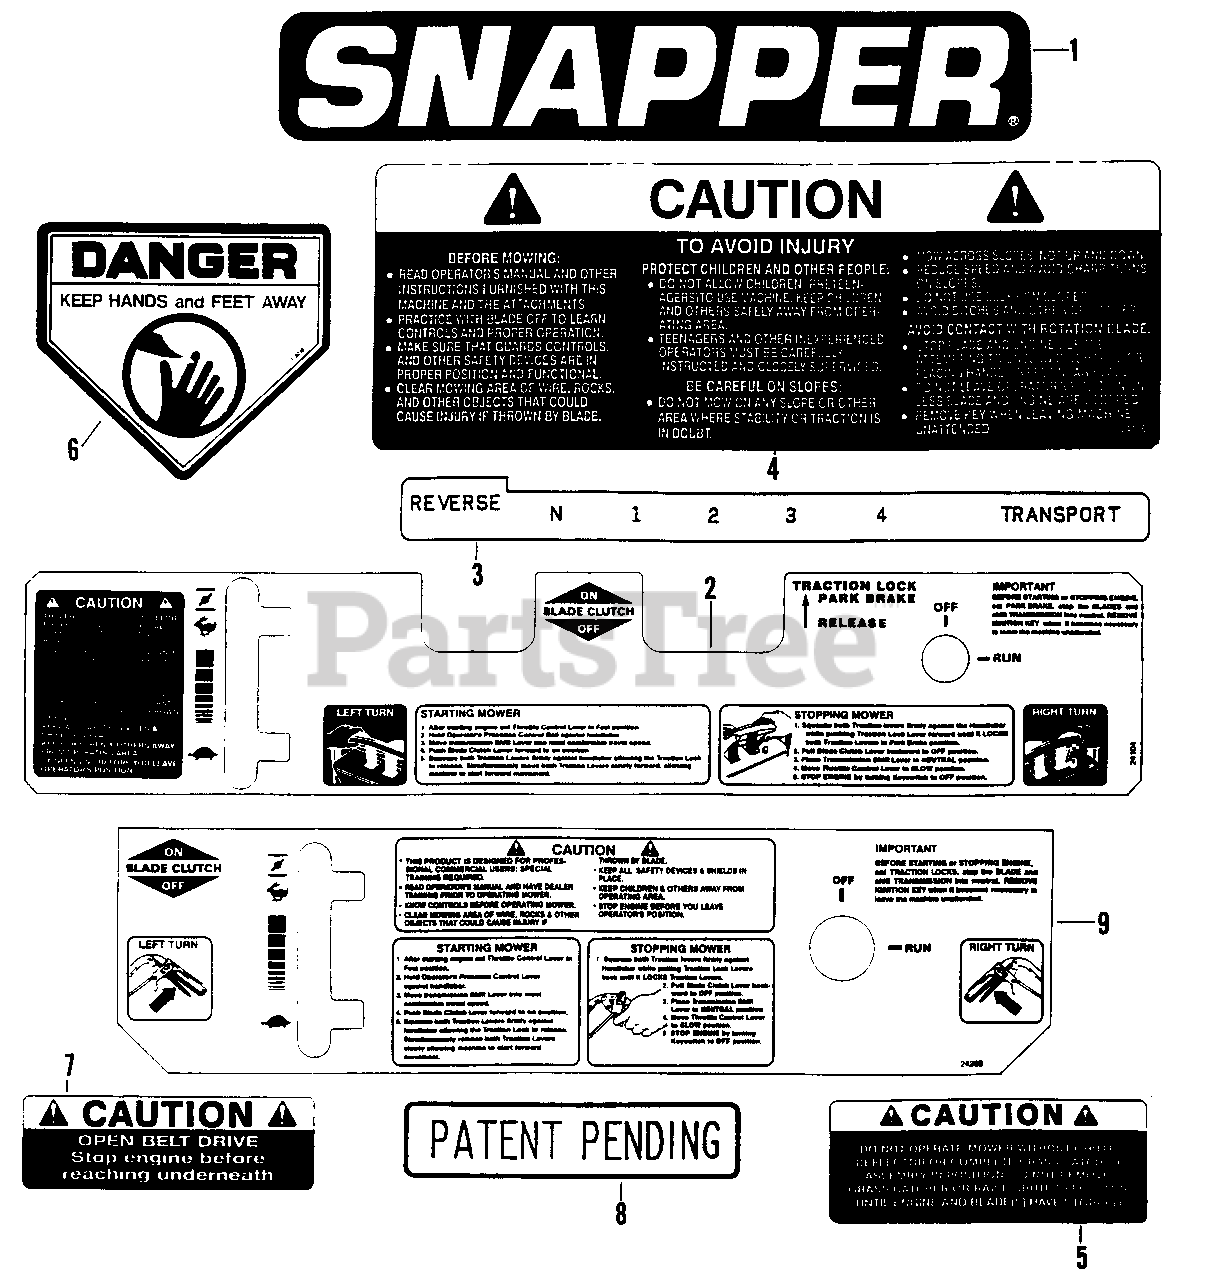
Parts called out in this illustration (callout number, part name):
1	DECAL, SNAPPER
2	DECAL, CONSOLE
3	DECAL, SHIFT QUAD
4	DECAL, CAUTION
5	DECAL, CAUTION
6	DECAL, WARNING
7	DECAL, CAUTION
8	DECAL, PATENT PENDING
9	DECAL, CONSOLE
